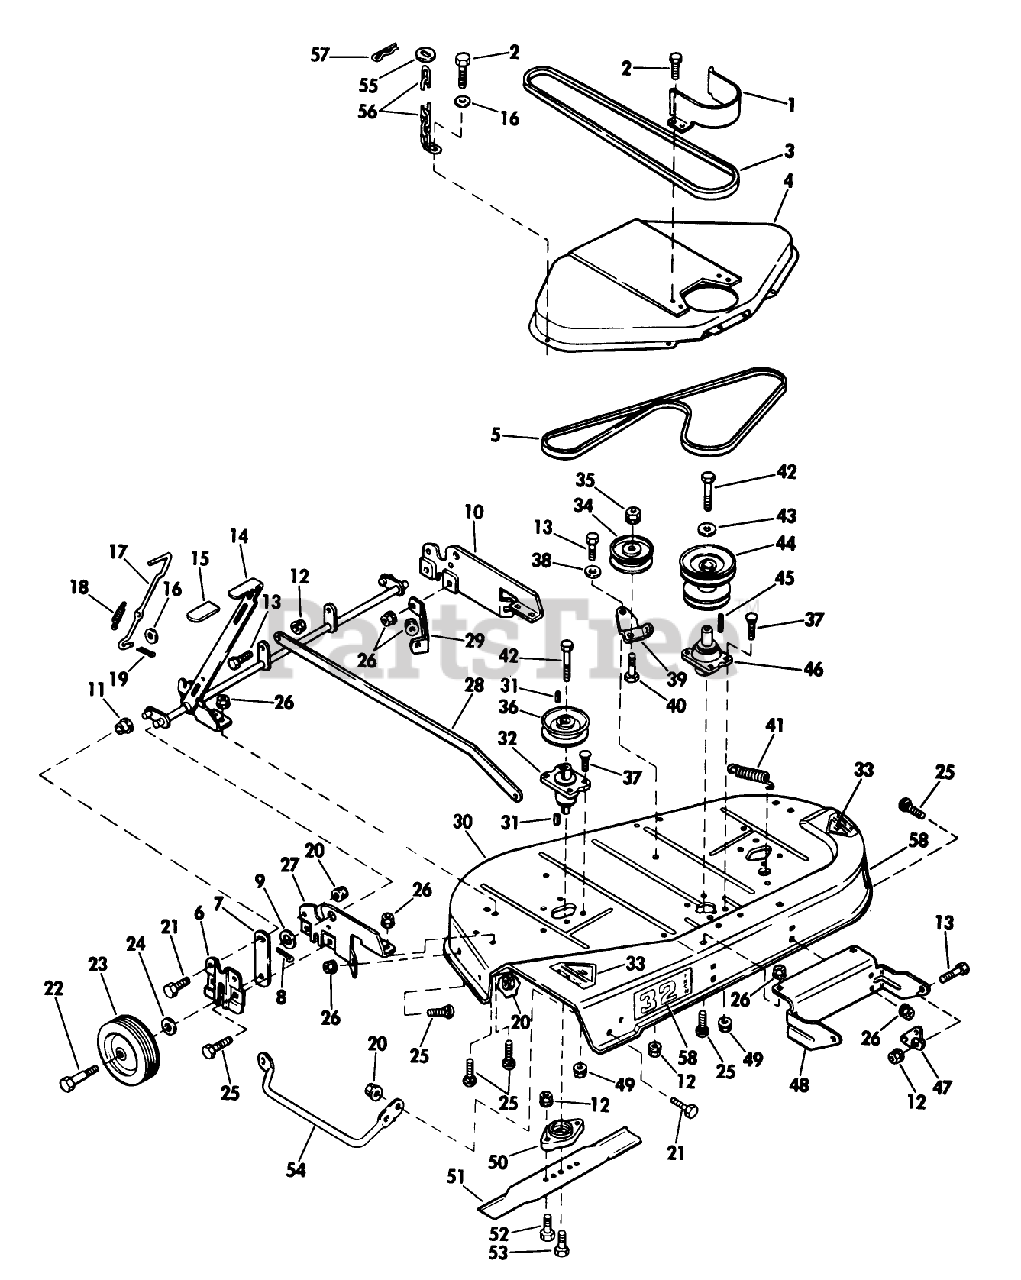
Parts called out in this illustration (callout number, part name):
2	Screw-Belt Cover
5	Throttle Control Assembly
6	Retainer-Height Adj. Slide
7	Slide-Height Adjuster
9	Washer-Height Adjuster
10	Bracket-Wheel Mounting L.H.
11	Bushing-Height Adjuster
14	Shaft Assembly Height Adjustment
15	Grip-Handle
17	Latch-Slide
18	Spring-Latch
20	STOP NUT
23	Wheel Tire Assembly
27	Bracket-Wheel Mounting R.H.
29	Brace-Wheel Mounting L.H.
31	Key-Bld-Spindle
34	Pulley-Idler
39	Lever-Idler
41	Spring-Idler
42	Screw-Nylok
47	Pivot-Blade Housing
49	Locknut-Large Flange
50	Adapter-Blade
52	Screw-Blade
53	Screw-Blade
